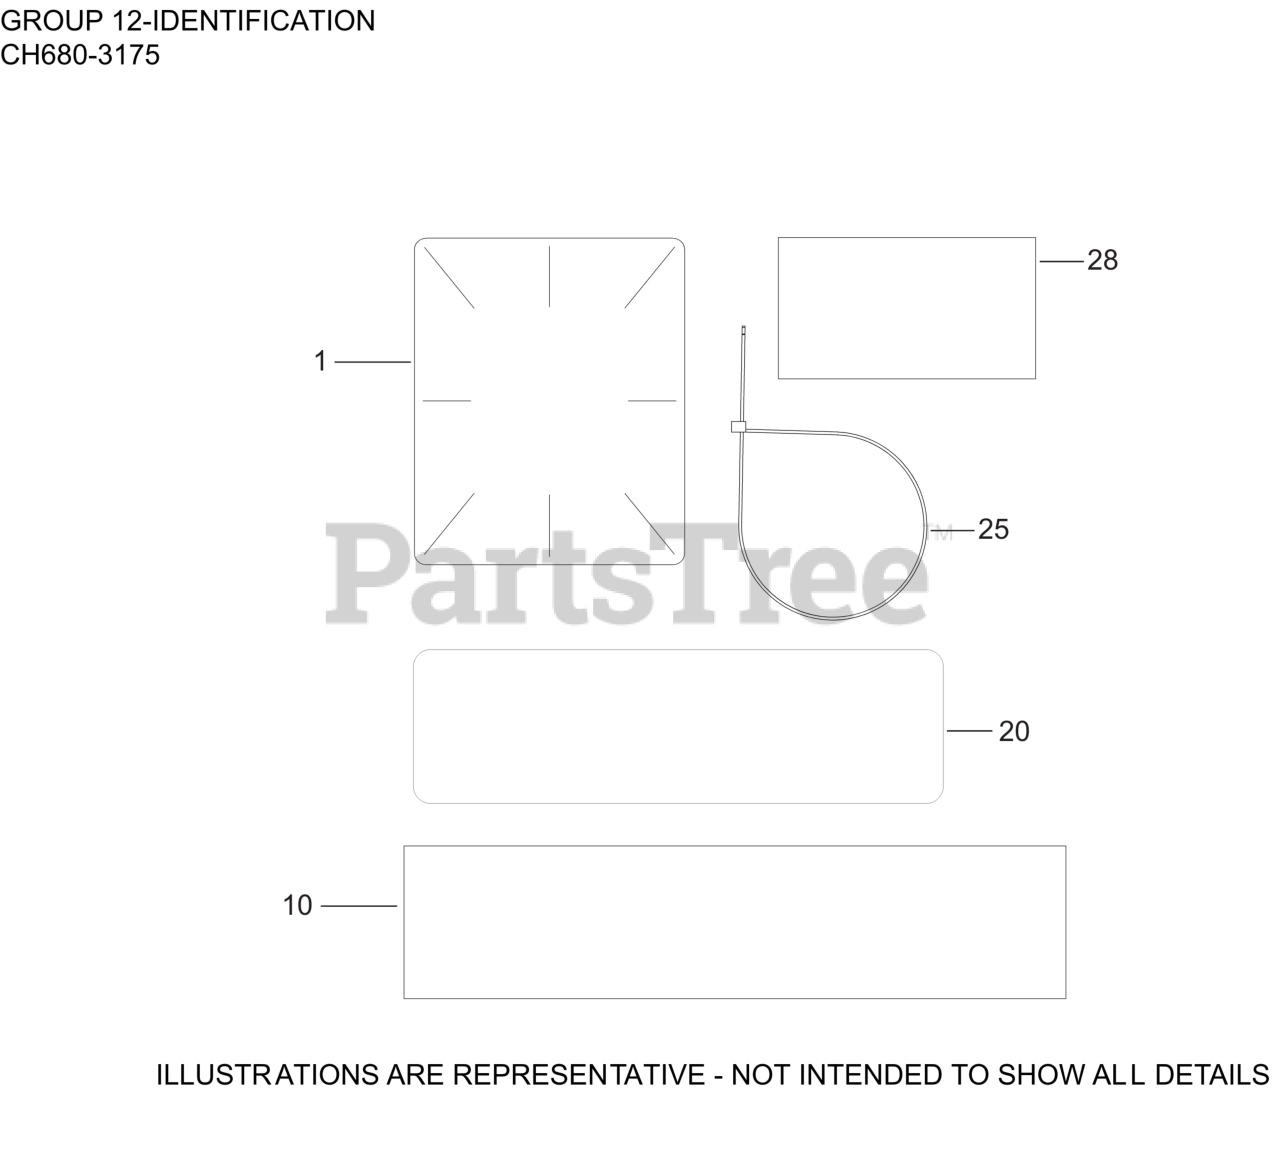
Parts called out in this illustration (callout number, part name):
1	LABEL, CLEAR LAMINATION
10	DECAL, STOPPING INSTRUCTION
20	DECAL LPAC, 22.5 HP/674cc/CH680
28	DECAL, USA
